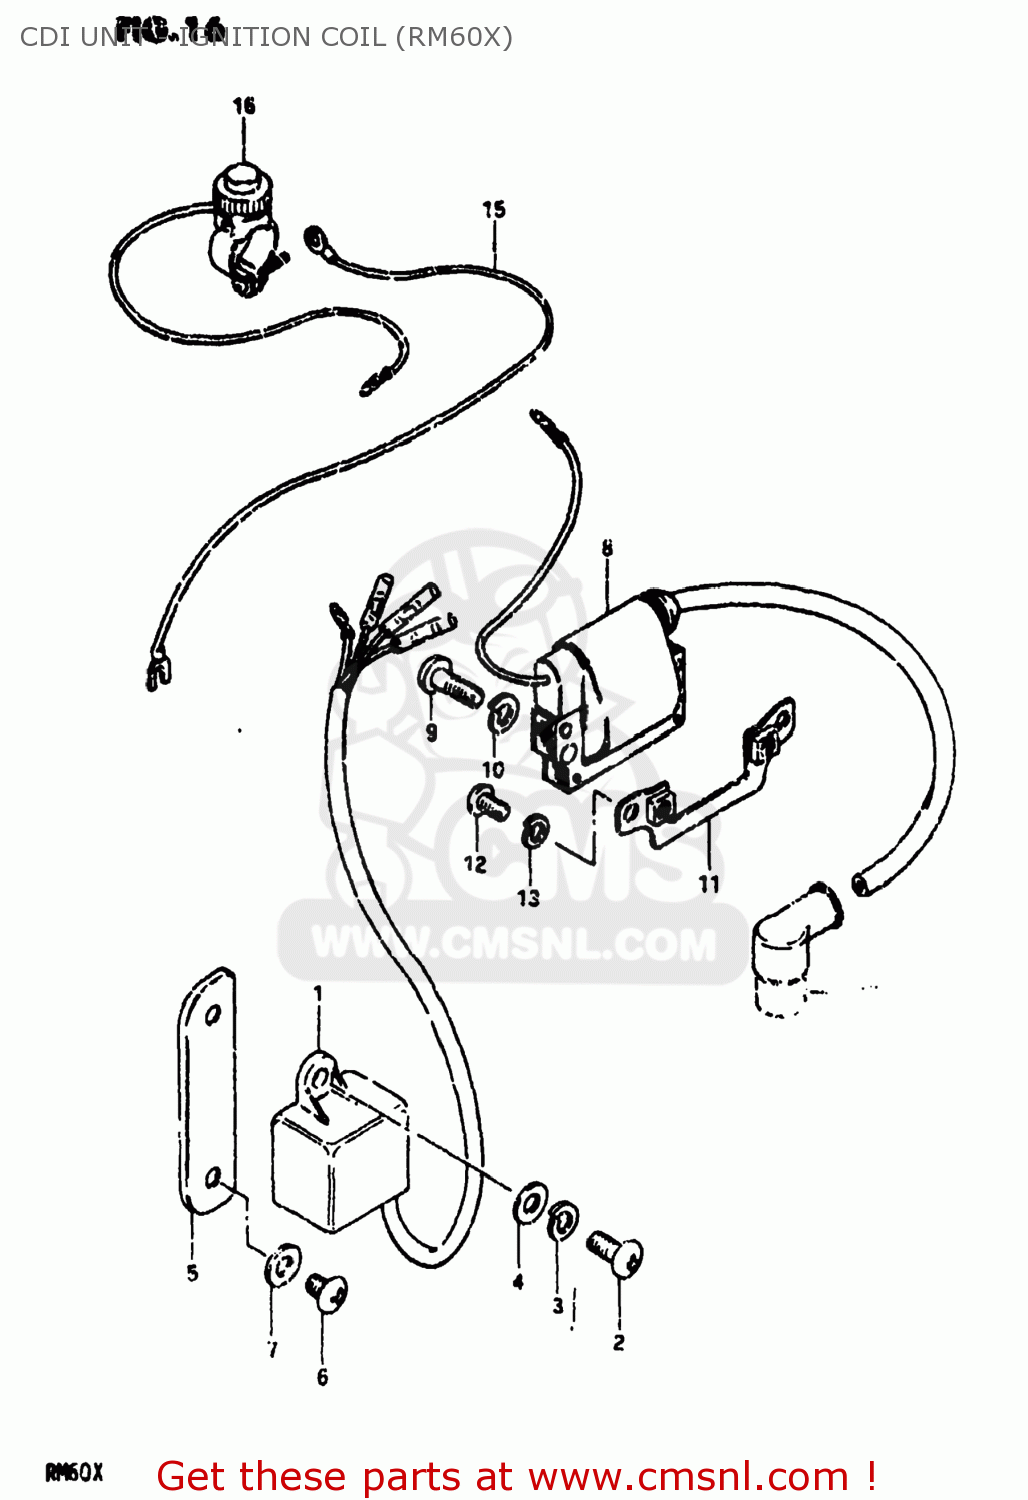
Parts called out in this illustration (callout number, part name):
1	CDI UNIT ASSEMBLY
2	SCREW
3	LOCK WASHER
4	WASHER
5	BRACKET,IGNITER
6	SCREW
7	WASHER
8	COIL ASSEMBLY,IGNITION
9	SCREW
10	LOCK WASHER
11	BRACKET,IGNITION COIL
12	SCREW
13	LOCK WASHER
14	CAP,SPARK PLUG
15	WIRE,ENGINE STOP EARTH
16	SWITCH ASSEMBLY
